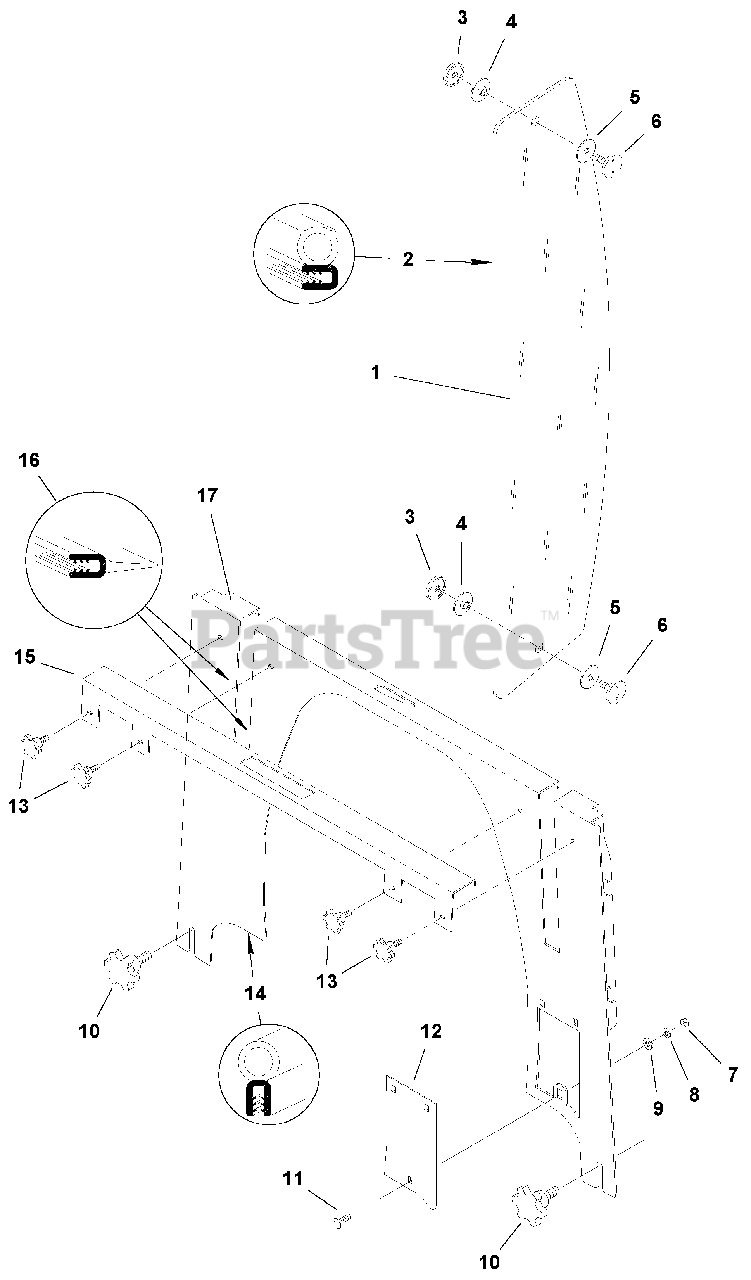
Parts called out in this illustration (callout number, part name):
1	WINDOW, Side
2	SEALING, Profile, 23 ft.
3	WASHER, with Bushing, M8
4	WASHER, Rubber with Socket
5	WASHER, Rubber
6	SCREW, Special, M8 x 20
7	NUT, Nylock
10	GRIP SCREW, 40/8 x 20
12	COVER, Frontshield
13	GRIP SCREW, 30/6 x 10
14	PROFILE SEALING, 1 ft. 4 in.
15	COVER, Front Shield Slots
16	GISTA RUBBER 30MM, 1 ft. 4 in.
17	CENTRAL FRONT SHIELD
